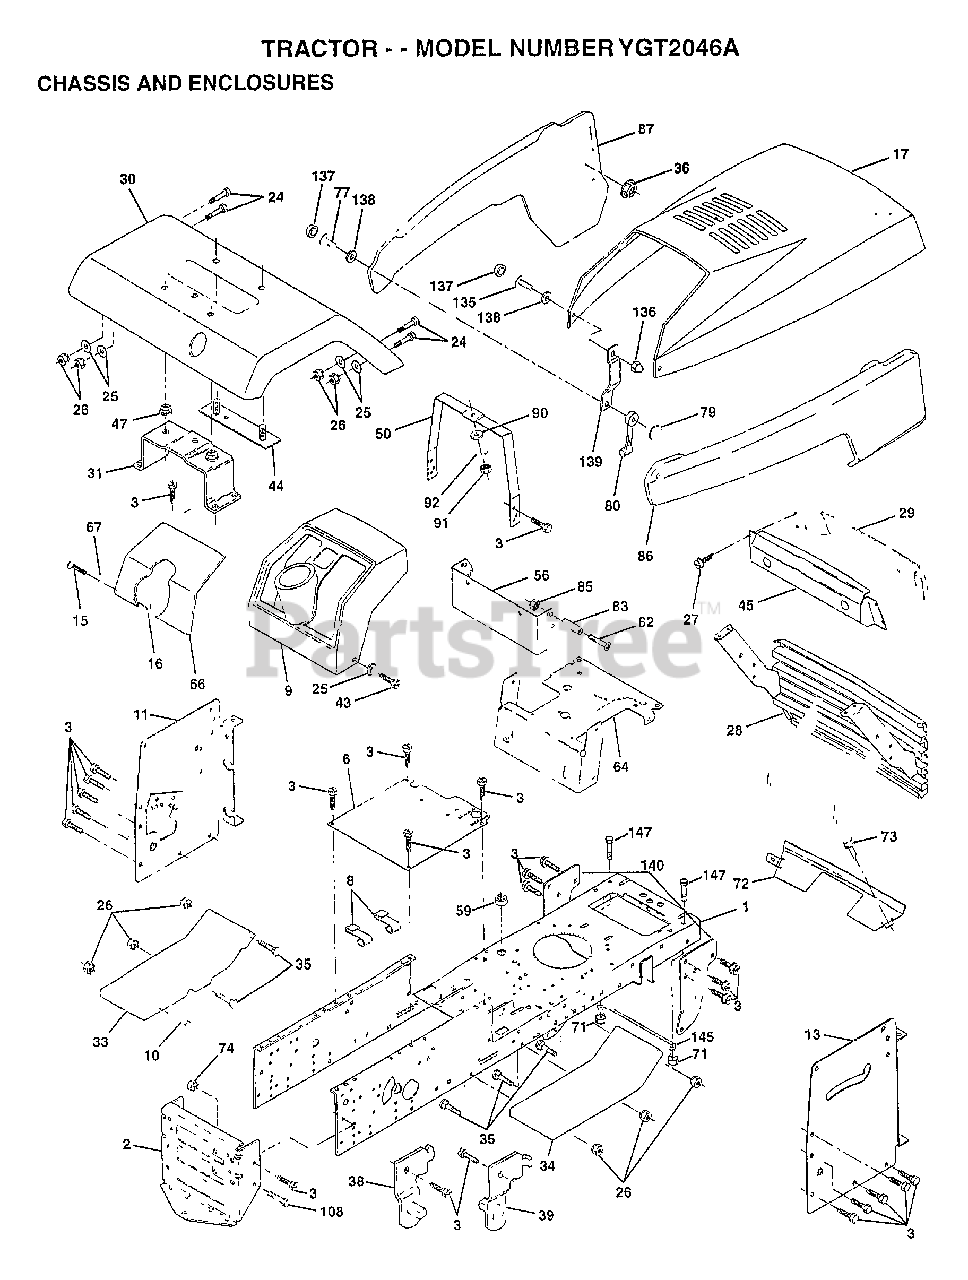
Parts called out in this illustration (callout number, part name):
1	CHASSIS ASM
3	SCREW
6	SADDLE
8	"CLIP,INSULATOR"
9	DASHBOARD BLACK
11	PANEL.DASH.LH.PNT
13	PANEL.DASH.RH.PNT
15	SCREW
17	"HOOD, YARD PRO"
24	BOLT
25	WASHER
26	NUT
28	GRILLE ASM PNT
29	LENS.BAR.CLEAR
30	"FENDER WS,FTK"
31	BRKT.ASM.FENDER
33	FOOTREST PNT LH
34	FOOTREST.RH.LT/GT
35	BOLT
36	PAL NUT LT
38	BRACKET ASM LH
39	BRACKET ASM RH
43	SCREW
44	STRAP ASM FENDER
45	BEZEL.ASM.
47	NUT-PUSH YT
50	DASH.SUPT.YP/HUSQ
56	EXT DASH LTYT
64	DASH.LOWER.LT
66	"PLATE DASH,SLKSCR"
67	WASHER
73	SCREW CRT
77	SCREW
79	WELDNUT
80	HOOD LATCH T
82	SCREW
83	SPACER LT
86	"PANEL ASM SIDE,RH"
87	"PANEL ASM-SIDE,LH"
90	WASHER PM
92	LOCKWASHER
135	SCREW.10-24X3/8.
136	ACORN NUT RB
137	SNAP CAP LT
138	WASHER LT
139	BKT.SPT.HOOD/PANL
140	BRKT SUSPENSION
145	"ROD POVOT,CHASSIS"
147	BOLT LT
